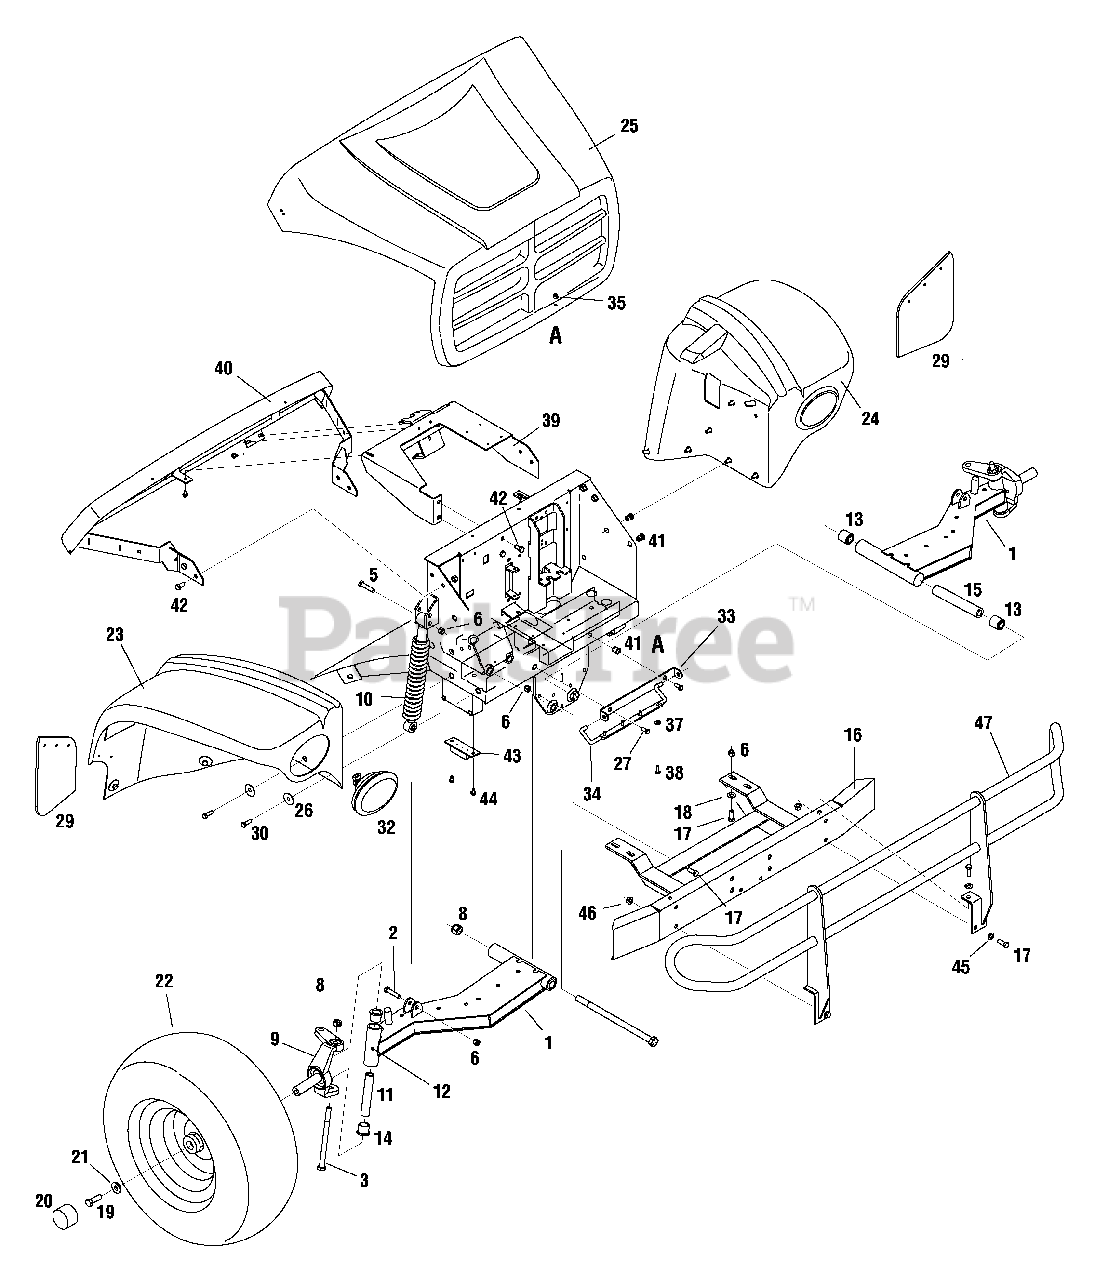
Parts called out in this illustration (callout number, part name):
1	Axle Assembly, Right-front
2	Hex Screw, 3/8-16 x 1.75
3	Hex Screw, 1/2-13 x 7.0, Gr5
4	Hex Screw, 5/8-11 x 11.13, Gr5
5	Hex Screw, 3/8-16 x 2.25
6	Nut, Hex Lock, Nylon, 3/8-16, Gr5
7	Nut, Hex Lock, Nylon, 5/8-11, Gr5
8	Nut, Hex Lock, 1/2-13
9	Steering Control Knuckle, RH
10	Shock Absorber, 2.9 Stroke
11	Tube, .875 x .50 x 4.75
12	Grease Fitting
13	Bearing, .63 ID x 1.19 OD
14	Bushing, Steering
15	Spacer, .645 ID x 1.063 OD
18	Flat Washer, .406 x .875 x .059
19	Hex Screw, 1/2-13 x 1.50, Gr5
21	Flat Washer, .531 x 1.25 x .181
22	RH Wheel Assembly, 22 x 11 x 10
23	Panel Assembly, Right Fender, Camo
24	Panel Assembly, Left Fender, Camo
25	Panel Assembly, Hood, Camo
26	Hex Screw 5/16-18 x 1.00 Gr 5
27	Hex Screw, 5/16-18 x .75
28	Flat Washer, .350 x 1.25 x .06
30	Washer, Bell, .39 x 1.38 x .062
31	Flat Washer, .194 x .62 x .063
32	Headlamp Assembly
35	Nut, Hex Lock, 1/4-20
36	Cotter Pin, Internal, 1.42
37	Washer, Flat, .271 x .63 x .065
38	Hex Screw, 1/4-20 x .75
41	Insert Nut, 5/16-18
42	Hex Screw, 3/8-16 x .75
43	Screw, Self-tapping, 1/4-20 x .5
44	Suspension Bumper
45	Washer, Flat, .406 x .812 x .051
46	Nut, Flange Lock, 3/8-16
47	Brush Guard
